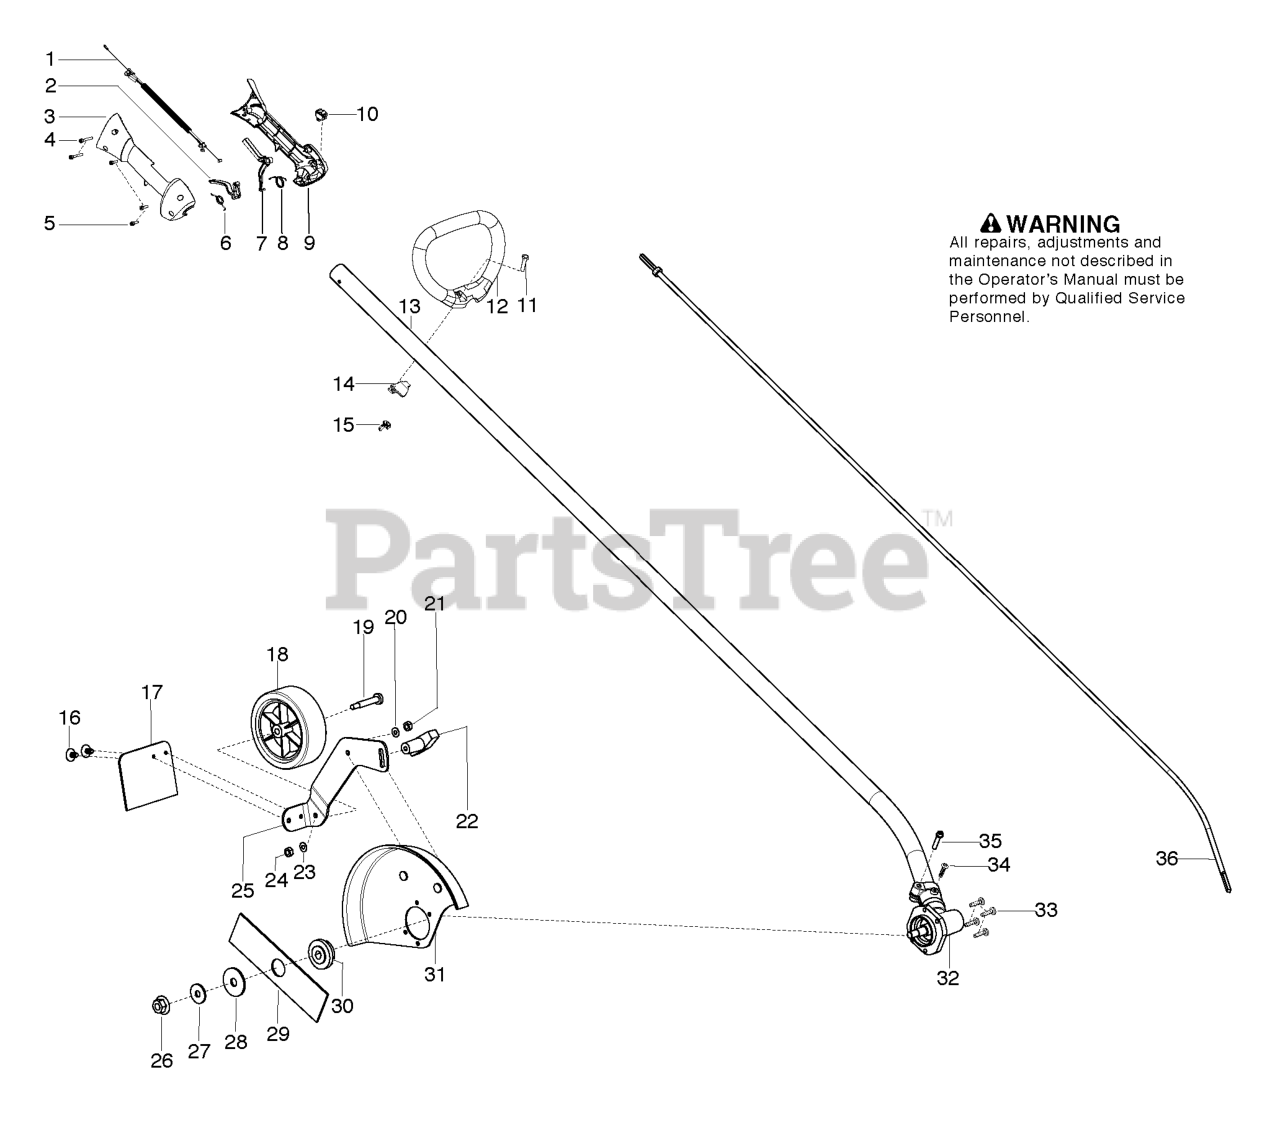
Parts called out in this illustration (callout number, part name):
1	%ASSY CABLE WIRE HARNESS
2	TRIGGER THROTTLE
3	HOUSING-THROTTLE RH
5	SCREW M4 X 1.75 PT 16MM
6	SPRING TRIGGER
7	THROTTLE LOCKOUT
8	SPRING LOCKOUT
9	HSG THROTTLE LH
10	KIT SWITCH
11	BOLT, TYPE 2
13	KIT-DRIVESHAFT
14	CLAMP ASSIST HANDLE
15	WINGNUT, TYPE 2
16	FASTENER MUD FLAP
17	KIT MUD FLAP
18	WHEEL-4"(FRONT)(RUBBER)
19	BOLT-SHOULDER AXLE
25	WHEEL BRKT ADJ
26	NUT-FLANGE (LH)
27	WASHER BELLVILLE
28	WASHER-FLAT.
31	KIT - EDGER GUARD
32	KIT GEARBOX EDGER HUSQ
33	SCR 10-24 MS LDK PAN PH
34	SCREW 8-16 X 9/16 (PLAS
35	SCREW - CARB. ADAPTOR
36	FLEXSHAFT 57"
